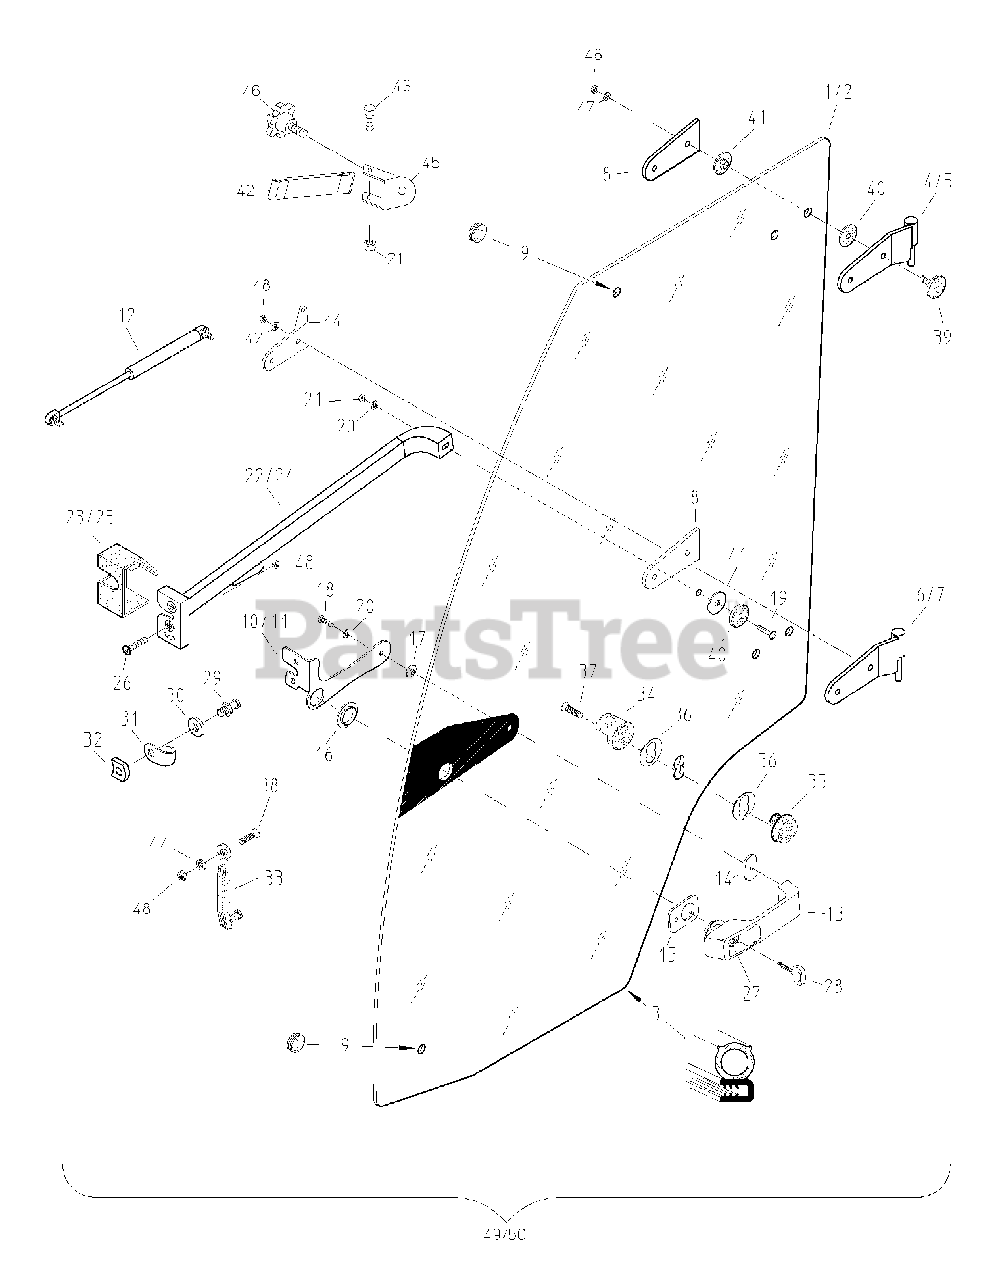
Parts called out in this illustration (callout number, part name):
1	LEFT DOOR, Glass
2	RIGHT DOOR, Glass
3	PROFILE SEALING, 23 ft. 3 in.
4	DOOR HINGE, Upper Right
5	DOOR HINGE, Upper Left
6	DOOR HINGE, Lower Right
7	DOOR HINGE, Lower Left
8	INNER BRACKET, Hinge
9	RUBBER STUBBLE, DM 16
10	LOCKER BRACKET, Left Door
11	LOCKER BRACKET, Right Door
12	GASLIFT, 320MM 300N
13	DOOR HANDLE, with Door Lock
14	RUBBER PAD, Small
15	RUBBER PAD, Large
16	RUBBER PAD, with Socket, Large
17	RUBBER PAD, with Socket, Small
22	INNER DOORLOCK, Left w/ Handle
23	DOOR LOCK COVER, Left
24	INNER DOORLOCK, Right w/ Handle
25	DOOR LOCK COVER, Right
28	KEY, (NR. 14603)
29	LOCKING BOLT, 13mm
31	GLIDE, Metal
32	BRACKET, Threaded
33	BAR, Door Holding
34	BEARING, Inner Gas Spring
35	BEARING, Outer Gas Spring
36	WASHER, Rubber
39	PVC-WASHER, with Screw, M8 x 30
40	WASHER, Rubber
41	WASHER, Rubber with Socket
49	LEFT DOOR, Complete, (Includes Ref. 2 - 41)
50	RIGHT DOOR, Complete, (Includes Ref 2 - 41)
